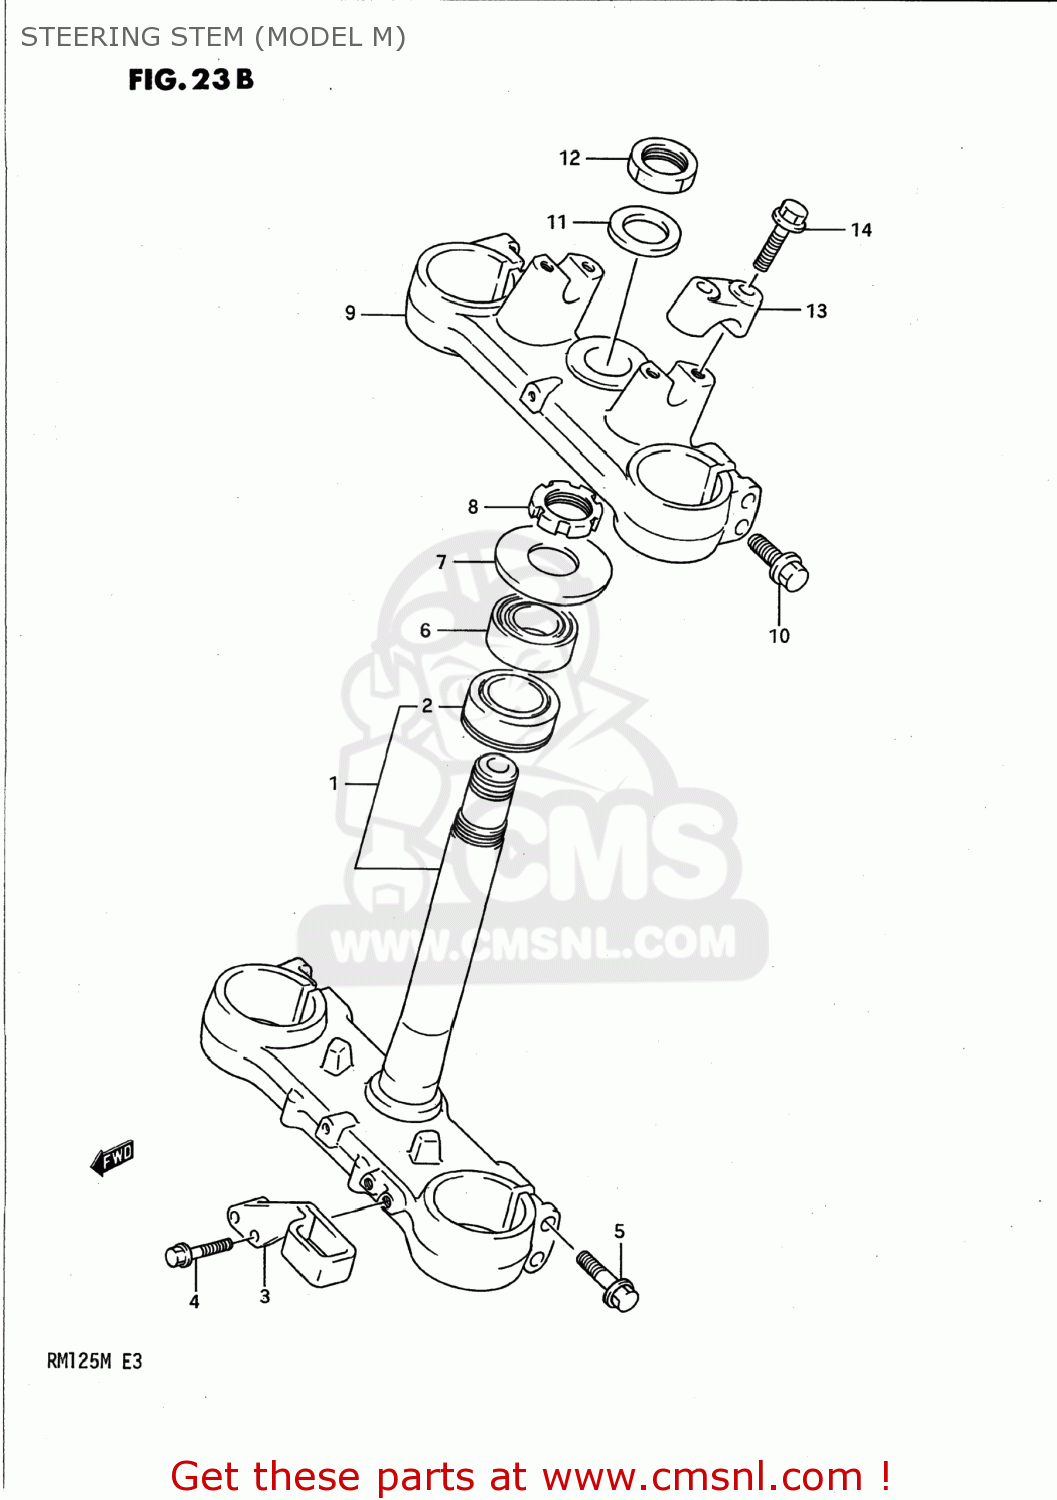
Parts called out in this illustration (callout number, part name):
1	STEM,STEERING
2	BEARING(30X52X16)
3	GUIDE,HOSE
4	BOLT,GUIDE
5	BOLT,STEM 8X45
6	BEARING
7	SEAL,STEERING,UPPER DUST
8	NUT,STEERING
9	HEAD,STEERING STEM
10	BOLT,STEM 8X45
11	WASHER,STEM HEAD
12	NUT,STEM HEAD
13	HOLDER,HANDLEBAR
14	BOLT,HANDLE HOLDER(8X35)
